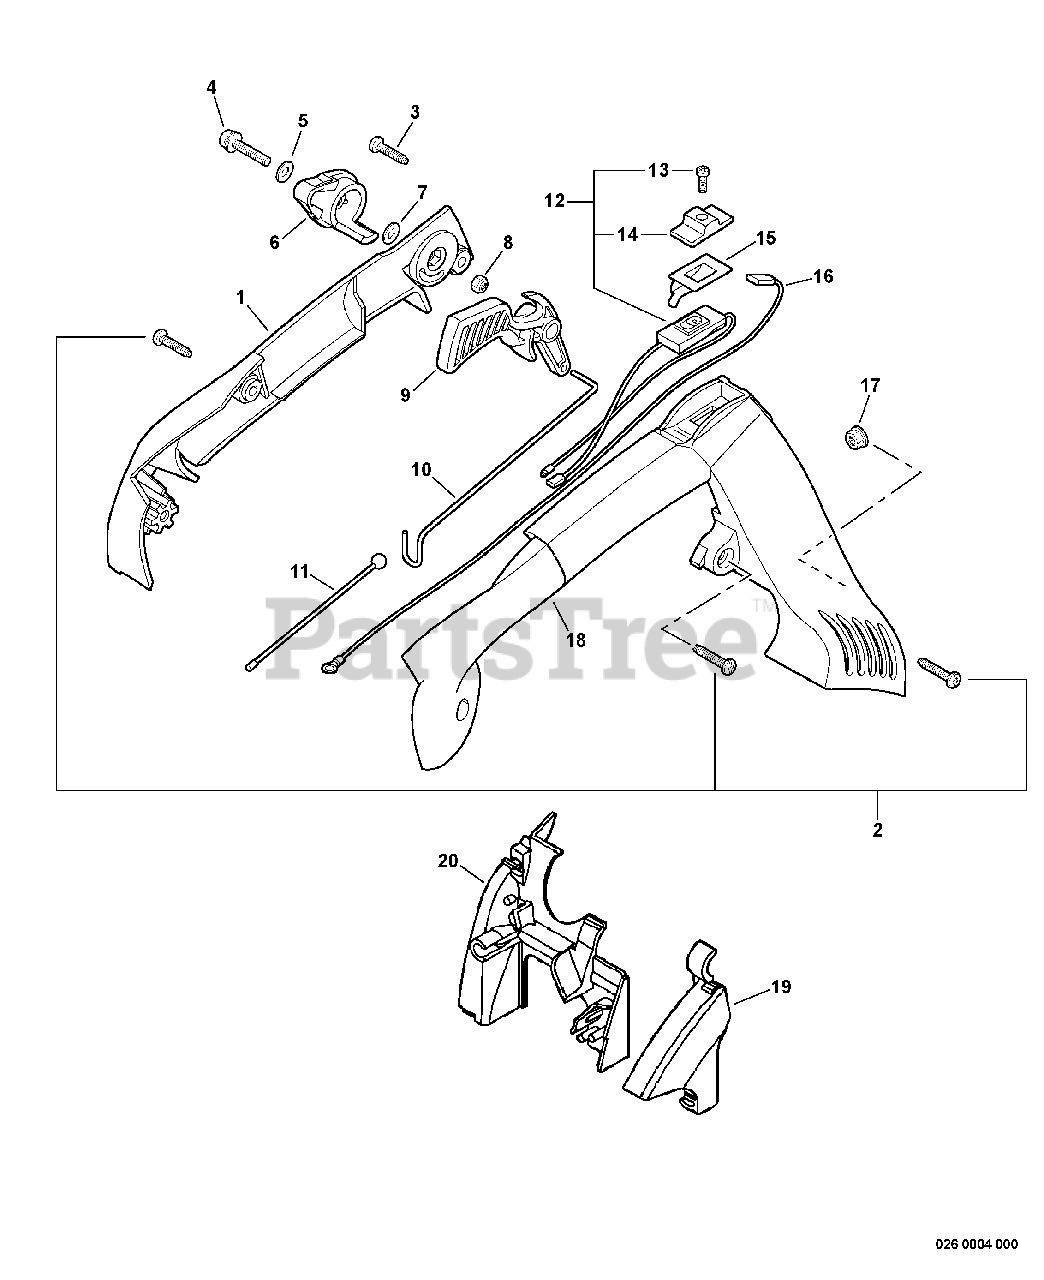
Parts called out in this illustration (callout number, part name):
1	COVER, HANDLE
2	SCREW - 5X20 -- TAPPING
3	SCREW - 5X20 -- TAPPING
4	SCREW - 5X25
5	WASHER - 5
6	LEVER, THROTTLE
7	WASHER - 5
8	LOCKNUT - 5
9	TRIGGER, THROTTLE
10	ROD, THROTTLE
11	CABLE, THROTTLE
12	IGNITION SWITCH ASSY
13	SCREW - 3X10
14	KNOB, SWITCH - ORANGE
15	TERMINAL - GROUND
16	LEAD - GROUND
17	NUT - 5 -- FLANGE
18	HANDLE - UPPER
19	COVER, THROTTLE
20	COVER, ENGINE
